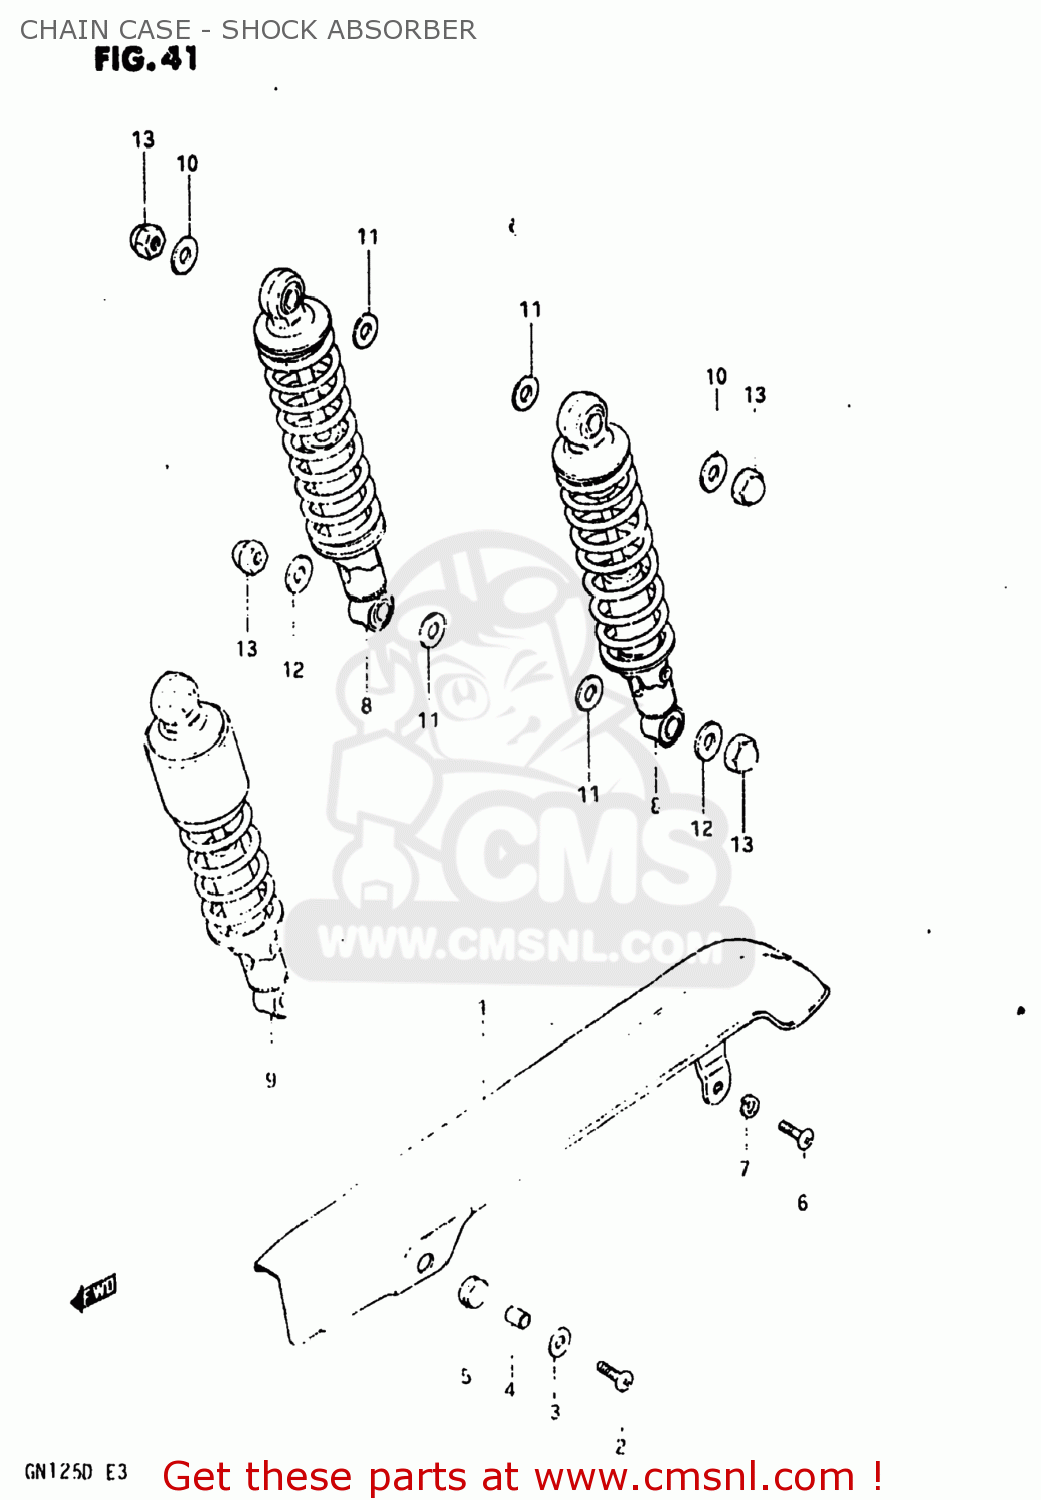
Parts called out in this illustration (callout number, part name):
1	CASE,CHAIN
2	SCREW
3	WASHER (6.5X20X1.2)
4	SPACER (7X9X7)
5	CUSHION
6	SCREW
7	LOCK WASHER
8	ABSORBER ASSY,RR SHOCK
9	ABSORBER ASSY,RR SHOCK
10	WASHER
11	WASHER (12.5X27X1.6)
12	WASHER
13	NUT, LOWER LH
